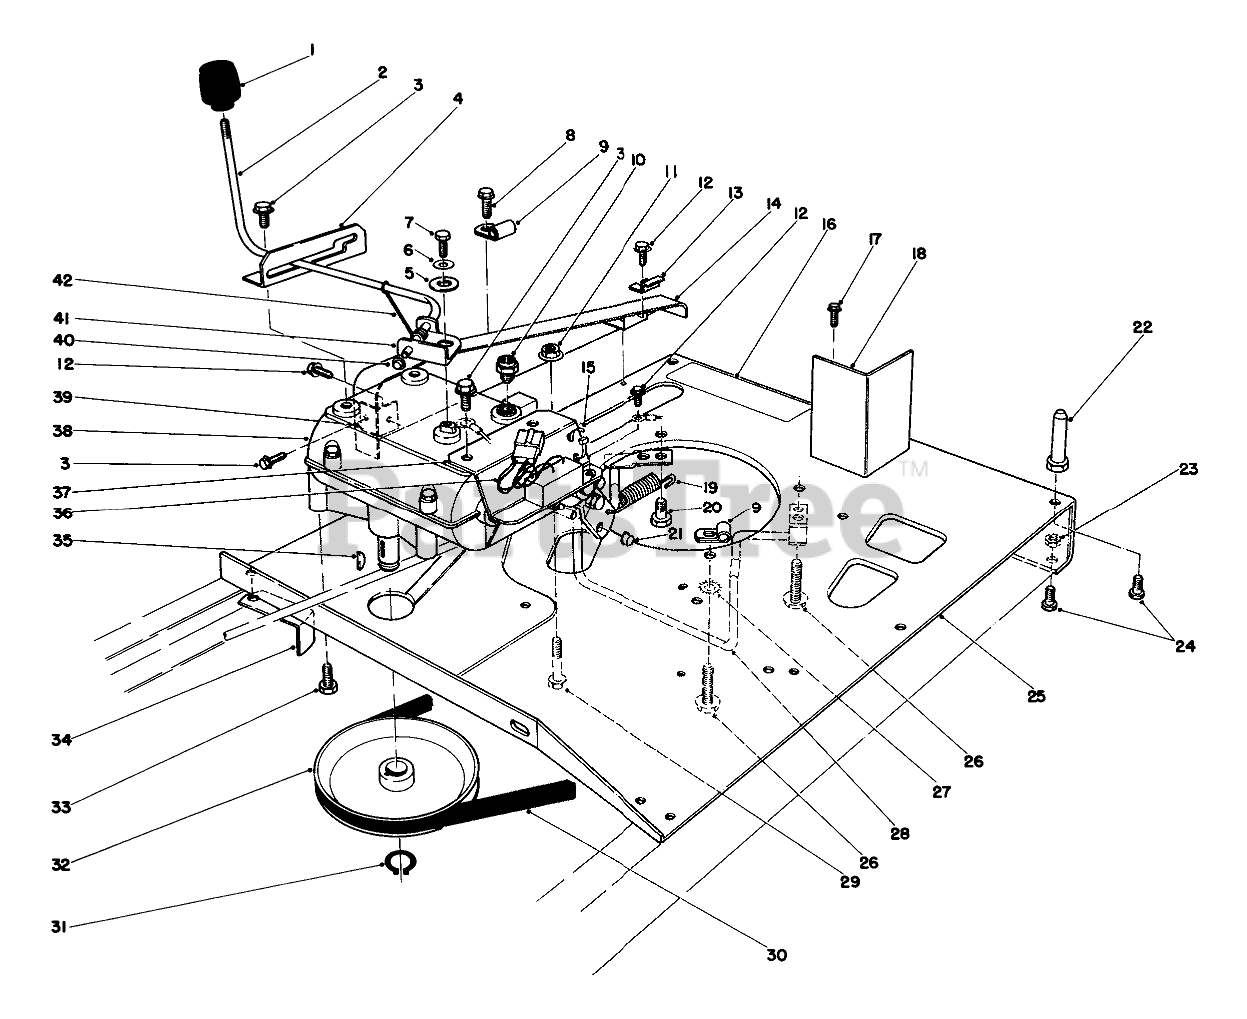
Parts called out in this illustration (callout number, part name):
2	SHIFT LEVER
3	SCREW-HWHTF
4	SHIFT LEVER GATE
5	WASHER-FLAT
6	PUSH-ON 93-3236
7	SCREW-HH
8	SCREW-HHFTF
9	CLIP-FUEL LINE
10	NEUTRAL SWITCH
11	NUT-HF
12	SCREW
13	Clamp-Cable
14	Chain Guard
15	TIE-CABLE
16	Decal
18	Baffle-Carb
19	SPRING-RETURN, BRAKE
20	Screw-HH
21	PUSH ON SPEED NUT 1/4
22	PIN-MOUNTING, LOWER
23	NUT-LOCK, CONE
24	SCREW-HH
25	Plate-Engine
26	SCREW-HWHTF
27	WASHER-LOCK
28	Belt Guide
29	SCREW-HH
30	V-BELT
31	RING-SNAP, EXTERNAL
32	Pulley
33	5/16-18 X 5/8 SEMS SC
34	TRANS BELT RET B
35	KEY-WOODRUFF
36	Control Module
37	Mount Module
38	TRANSMISSION
39	CHAIN GUARD BRKT B
40	RETAINER-PUSH ON
41	SHIFT LEVER CLAMP
42	Spring-Shift Rod
